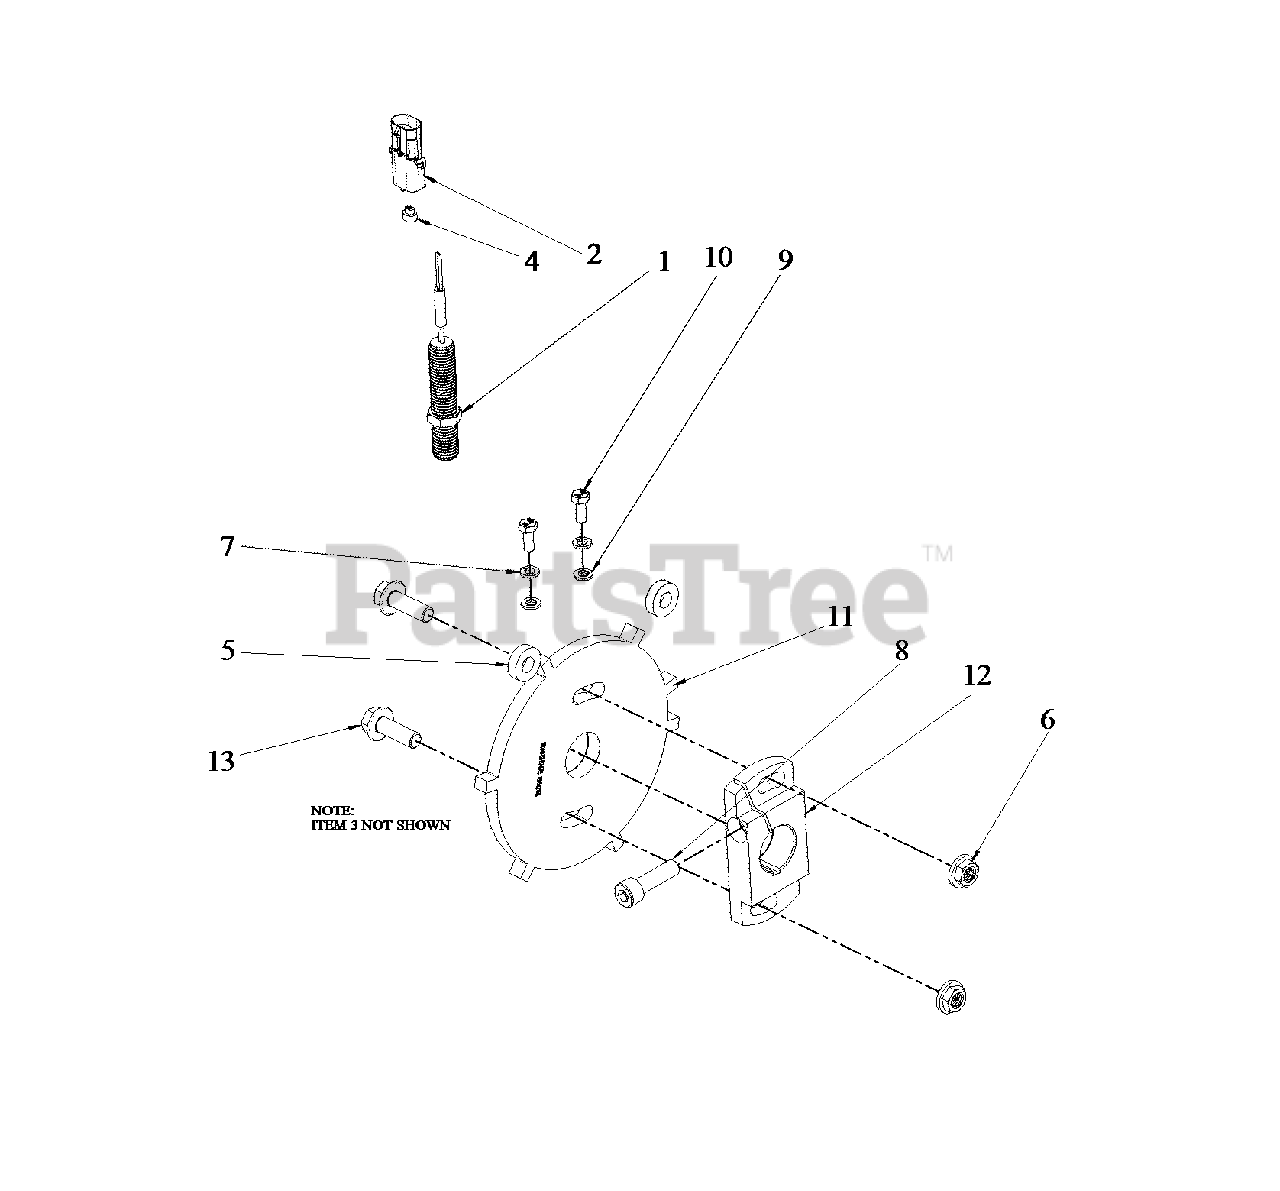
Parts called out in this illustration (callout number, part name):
1	SENSOR
2	CONNECTOR
4	SEAL
5	* WASHER
6	* NUT
7	* WASHER
8	* BOLT
9	* WASHER
10	* BOLT
11	* CAM WHEEL
12	* ADAPTER
13	* BOLT
